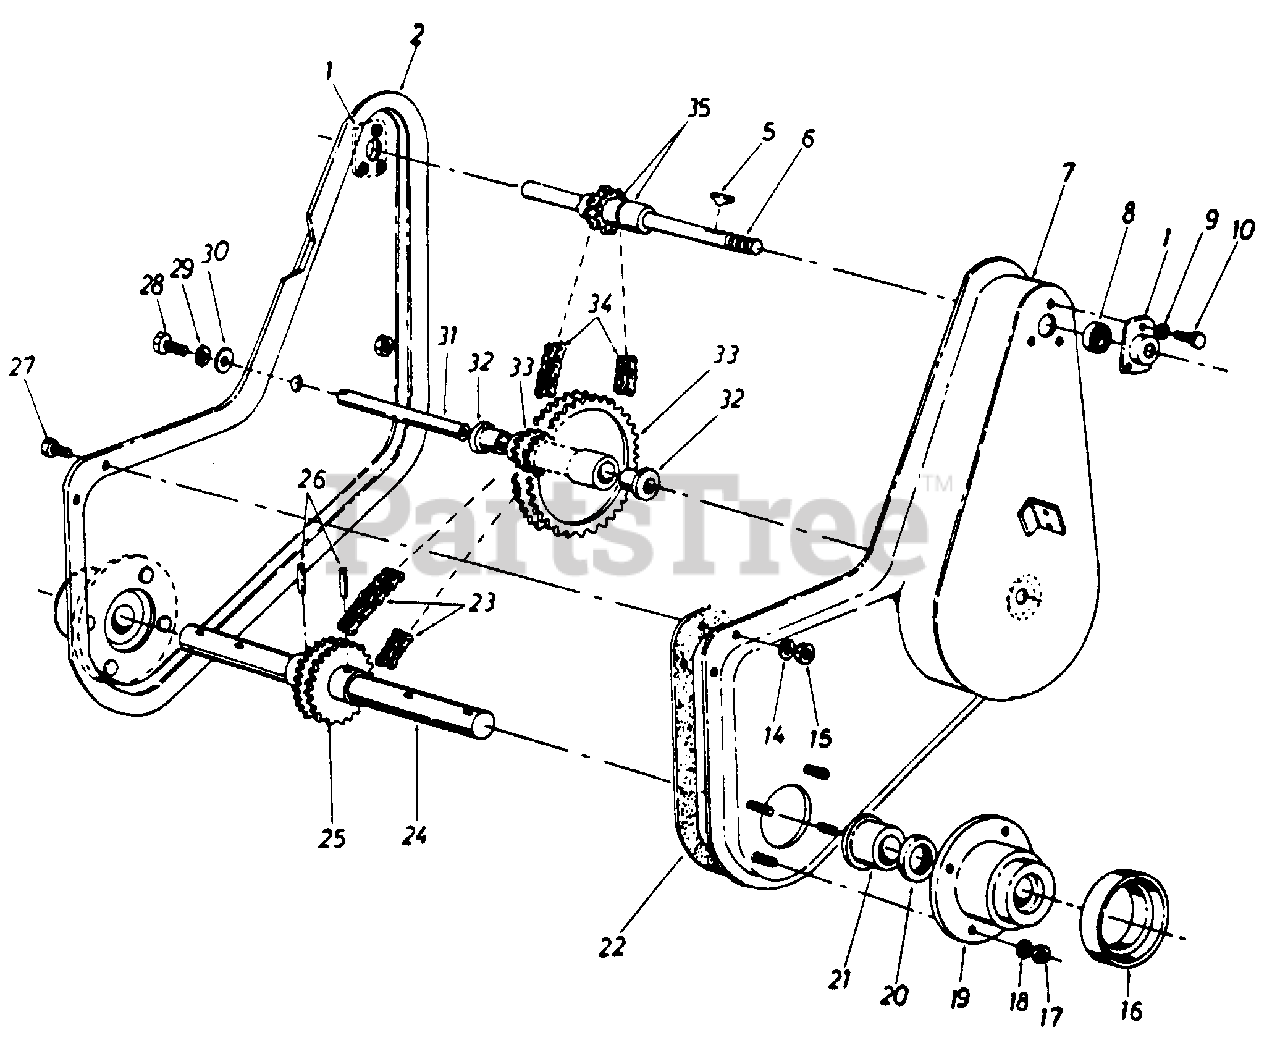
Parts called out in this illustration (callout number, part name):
1	Bearing Housing 1.375" Dia.
6	Input Shaft Assembly
9	L-Wash. 1/4" I.D.
10	Hex Bolt 1/-20 x .62" Lg.
14	L-Wash. 1/4" I.D.
15	Hex Cent. L-Nut 1/4-20 Thd.
16	Dust Cap Cover
17	Hex Cent. L-Nut 5/18-18 Thd.
18	L-Wash. 5/16" I.D.
19	Cast Bearing Housing
20	Oil Seal
21	Flange Bearing 1.25 I.D. x 1.75 O.D.
22	Gasket
23	Roller Chain #40-2 x 34.0 Lg.
24	Tine Shaft
25	Double Sprocket T24-2 Teeth 1/2 Pitch
26	Spiral Pin 3/8 Dia. x 2.00 Lg.
27	Hex Bolt 1/4-20 x .62 Lg.
28	Hex Bolt 5/16-18 x .75 Lg.
29	L-Wash. 5/16 I.D.
30	Fl-Wash. 5/16" I.D.
31	Sprocket Shatt
32	Flange Bearing .62 I.D. x .75 O.D.
33	Double Sprocket Assembly
34	Roller Chain #35-2 x 36.75 Lg.
35	Spacer 5/8 I.D. x /8 O.D.
